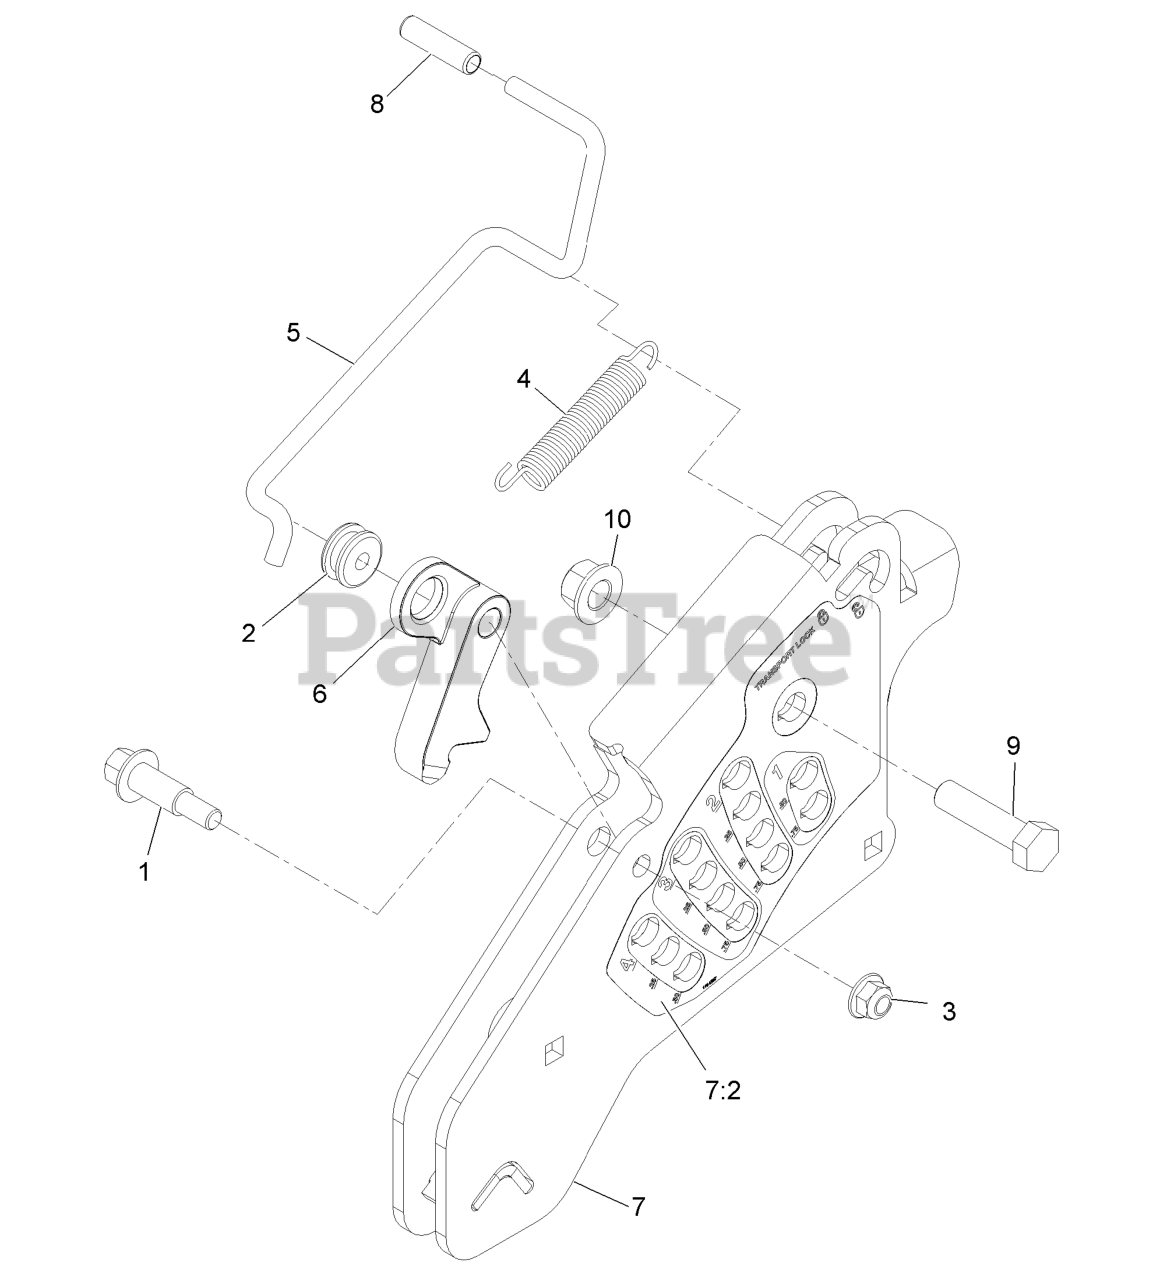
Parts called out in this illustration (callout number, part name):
1	BOLT-SHOULDER
2	GROMMET
3	NUT-HF, NI
4	SPRING-EXTENSION
5	ROD-LOCK, TRANSPORT
6	PAWL-TRANSPORT, HOC
7	HOC PLATE ASM
7:2	DECAL-HOC
8	GRIP-LEVER
9	SCREW-HH
10	Nut-Lock 1/2-13
